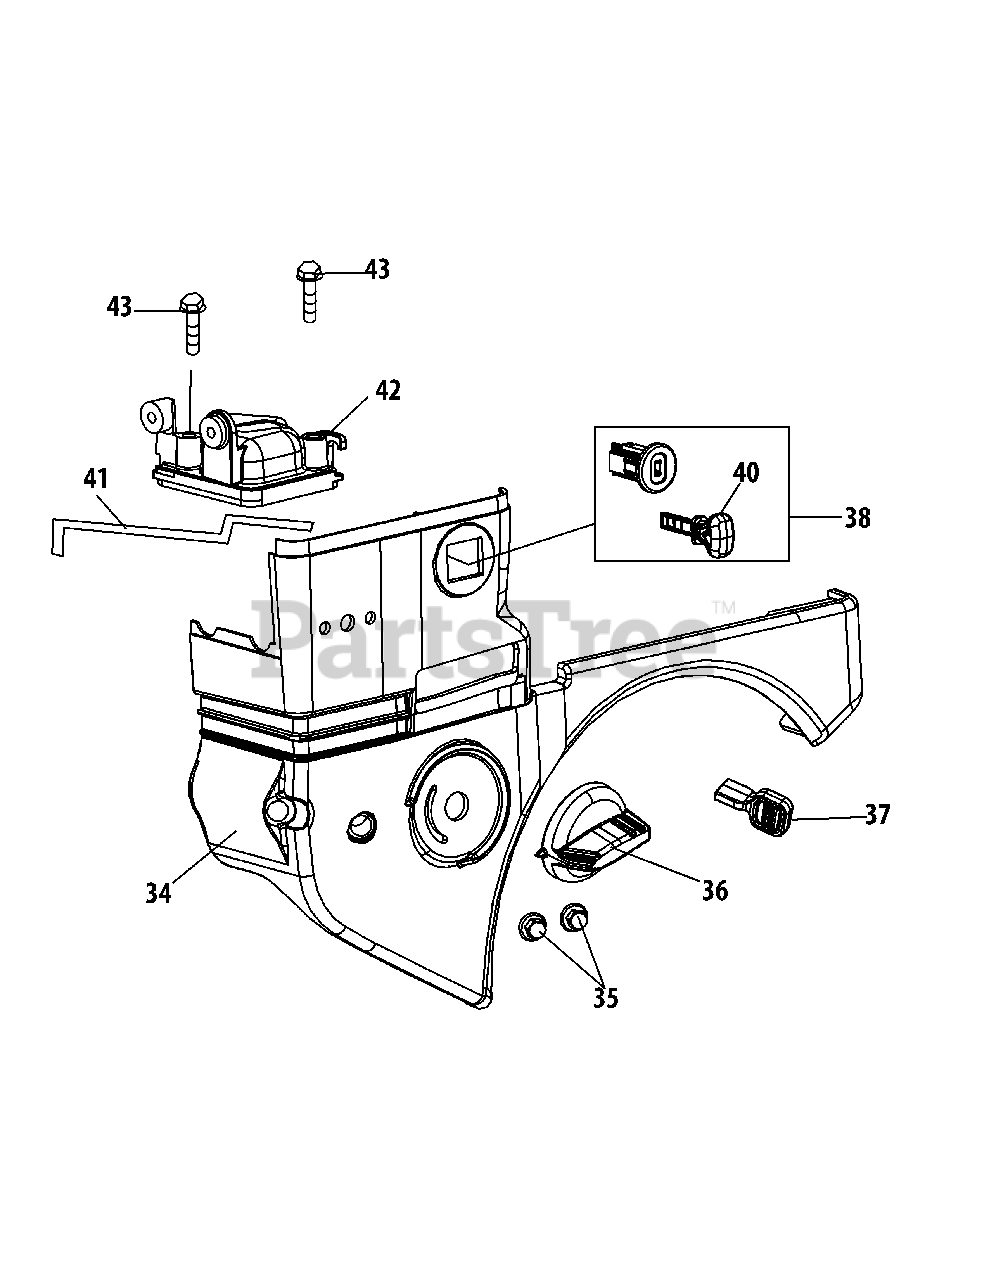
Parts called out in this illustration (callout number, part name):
34	Engine Shroud
36	Choke Knob
37	Throttle Control Knob
38	Key Switch
40	Key
41	Choke Push Rod
42	Heater Box
43	Bolt M6×28
